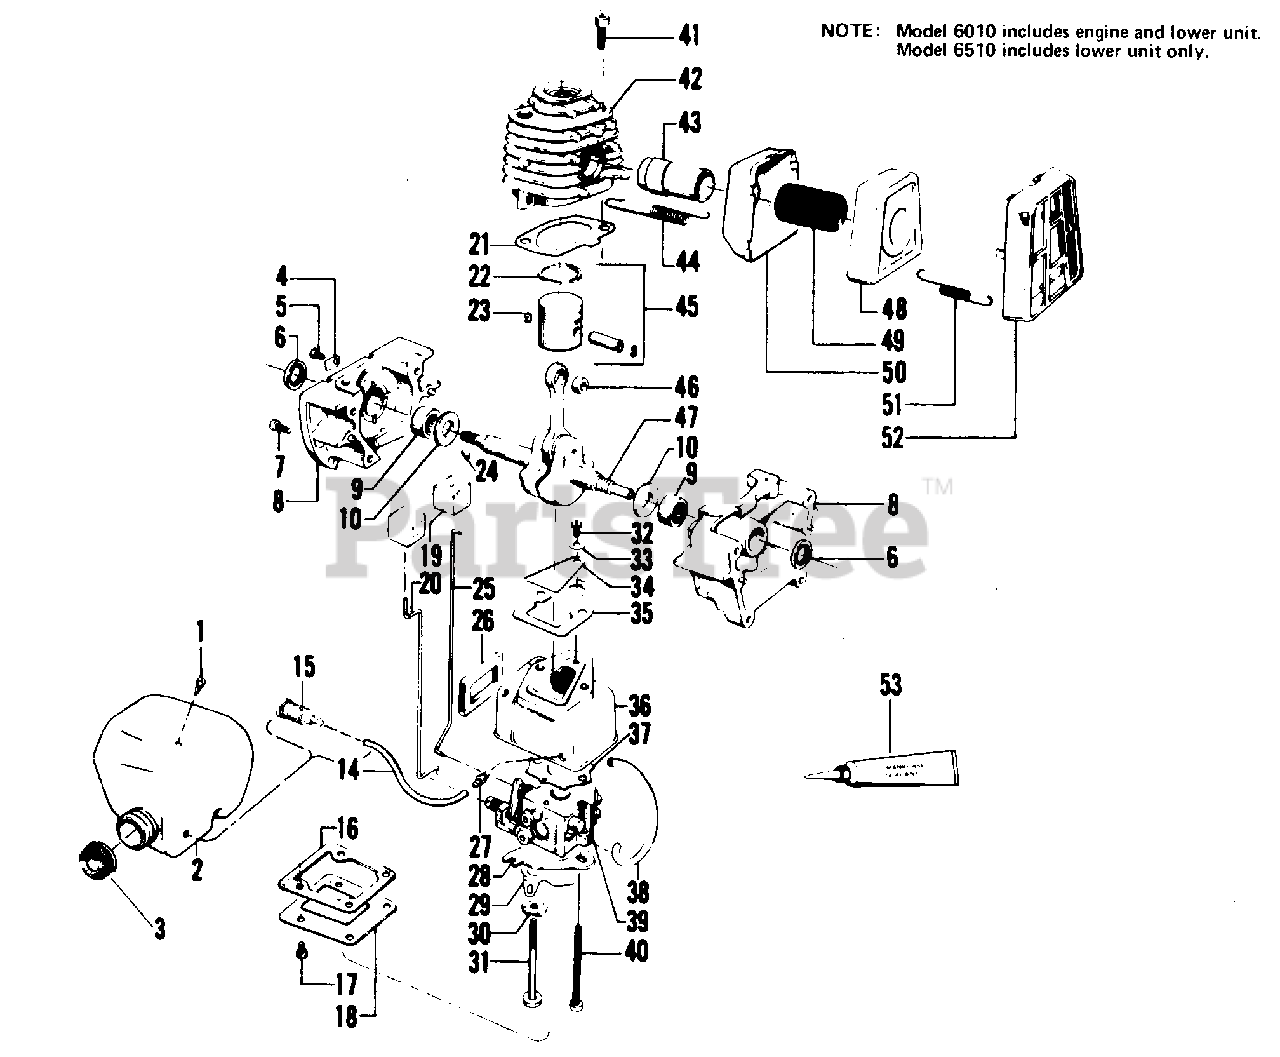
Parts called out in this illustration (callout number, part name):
1	Check Valve - Duck Bill
2	Fuel Tank Assembly (Inc. # 1, 3, 14 & 15)
3	Fuel Cap Assembly (Inc. O-Ring)
4	Clamp - Choke Wire
5	Screw - 8 - 32 x 5/16 - Choke Rod Clamp
6	Seal - Crankcase
7	Screw - Crankcase
8	Crankcase Assembly (Inc. # 6 & 9)
9	Bearing - Crankcase
10	Washer - Thrust - Crankshaft
14	Fuel Line
15	Fuel Pick-up Assembly
16	Gasket - Carburetor Case Cover
17	Screw - 8 - 18 x 9/16 - Pan Hd. - Carburetor Case Cover
19	Boot - Throttle - Choke Wire
21	Gasket - Cylinder
22	Ring - Piston
23	Retainer - Wrist Pin
24	Key - Flywheel
25	Throttle Wire
26	Seal - Carburetor Case
27	Fuel Line Fitting
29	Choke Shutter
30	Washer - Wave
31	Screw - 10 - 24 x 2-1/8 - Fil. Hd. - Carburetor Shoulder
32	Screw - 6 - 19 x 5/16 - Pan Hd. - Reed Valve
33	Washer - Reed Valve Screw
34	Reed Valve
35	Gasket - Carburetor Case to Crankcase
36	Carburetor Housing
37	Gasket - Carburetor
38	Fuel Line - Carburetor
39	Carburetor - See Service Ref. 2.
40	Screw - 10 - 24 x 1-7/8 - Fil. Hd. - Carburetor
41	Screw - 1/4 - 20 x 3/4 - Hex Socket Hd. - Cylinder
42	Cylinder
43	Diffuser - Muffler
44	Spring - Muffler Attachment
45	Piston Assembly (Inc. # 22, 23 & Pin)
46	Bearing - Wrist Pin
47	Crankshaft & Rod Assembly
48	Cover - Muffler Cover - Muffler
49	Screen - Spark Arresting
50	Body - Muffler
51	Spring - Muffler Guard
52	Guard - Muffler
53	Sealant - Crankcase (Not Supplied With Unit)
